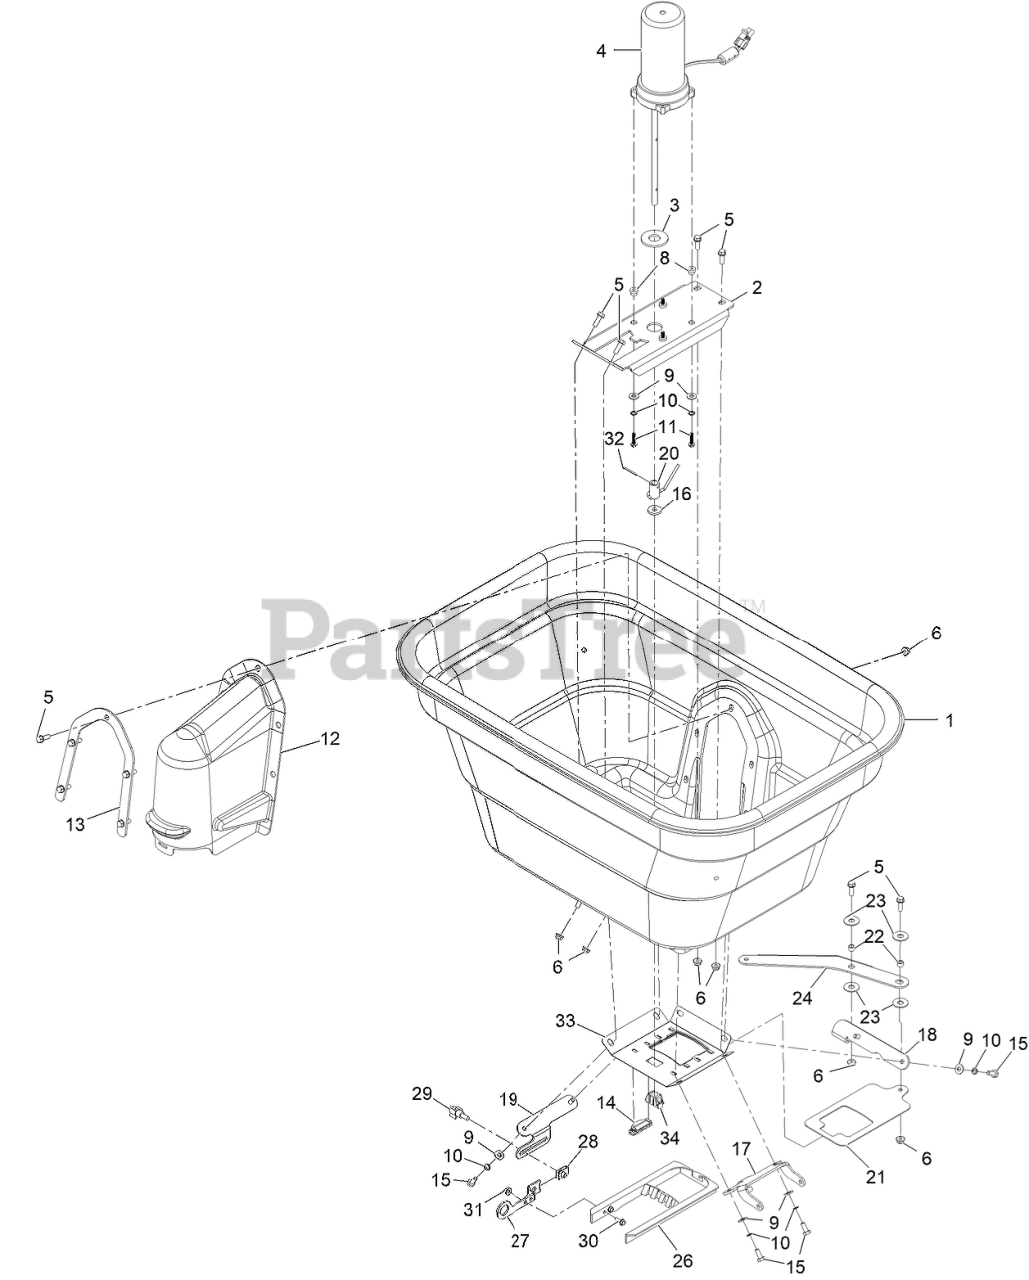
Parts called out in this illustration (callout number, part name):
1	Hopper-Spreader, 175 Lb
2	MOUNT-MOTOR
4	MOTOR-SPREADER
5	SCREW-HWH
8	SPACER-FLANGED
9	WASHER-FLAT
10	WASHER-LOCK, INT
11	SCREW-SHWH
12	COVER-MOTOR
13	SUPPORT-COVER
14	GUIDE-RATE, GATE
15	SCREW-HH
16	WASHER-FELT
17	MOUNT-DEFLECTOR
18	MOUNT-GATE, PIVOT
19	MOUNT-GATE, PIVOT
20	WELD-AGITATOR
21	GATE-SPREADER SEED
24	ARM-ENGAGEMENT
26	DIFFUSER-ACCESSORY
27	BRACKET-ACCUWAY, SLIDE
29	KNOB-STAR, THREE
31	NUT-LOCK, FLANGE
32	Pin-Cotter
33	BOTTOM-MULCH
34	HOPPER BOTTOM BEARING
